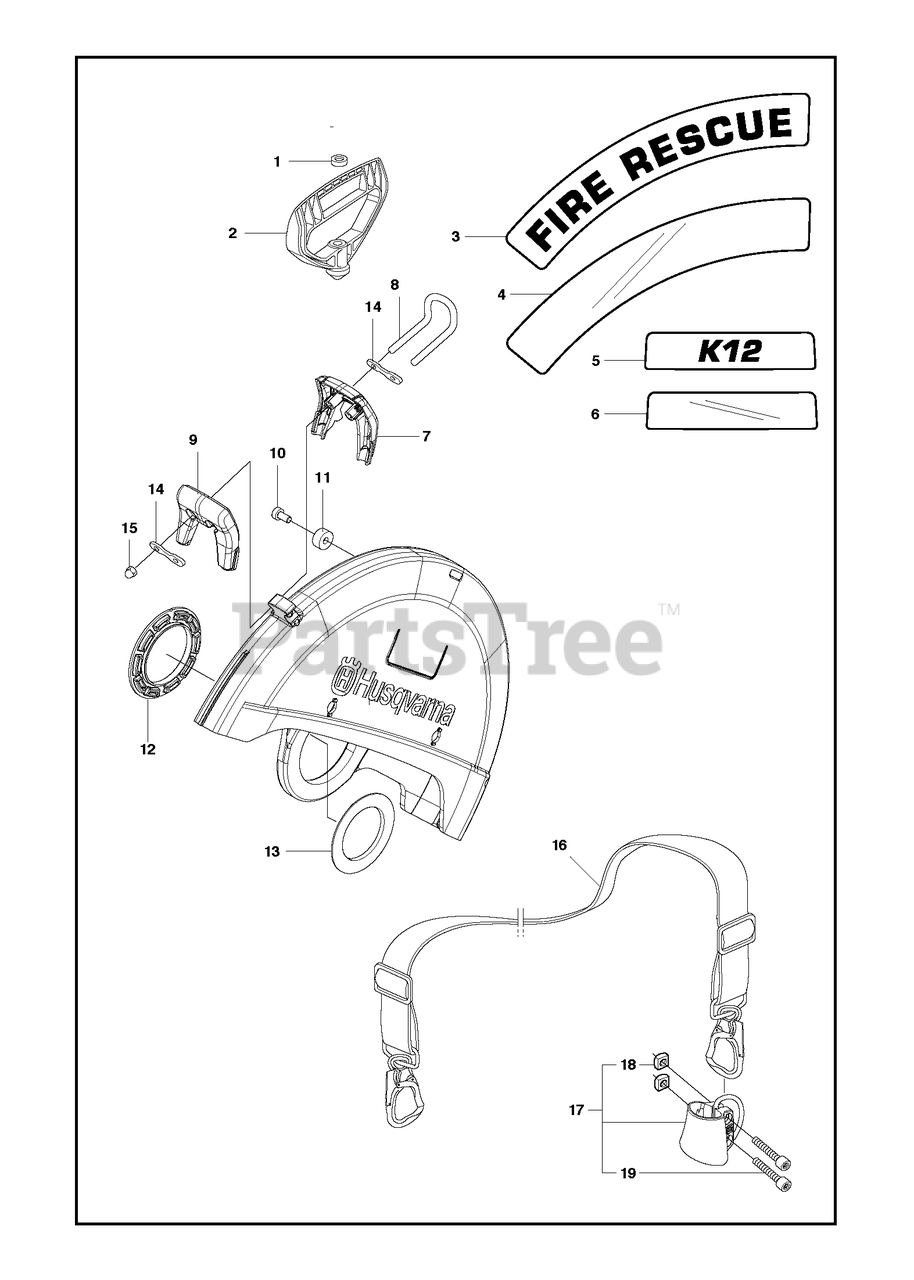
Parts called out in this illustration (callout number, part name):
2	STARTER HANDLE
10	SCREW ITXSCT
19	SCREW ITXSCM
